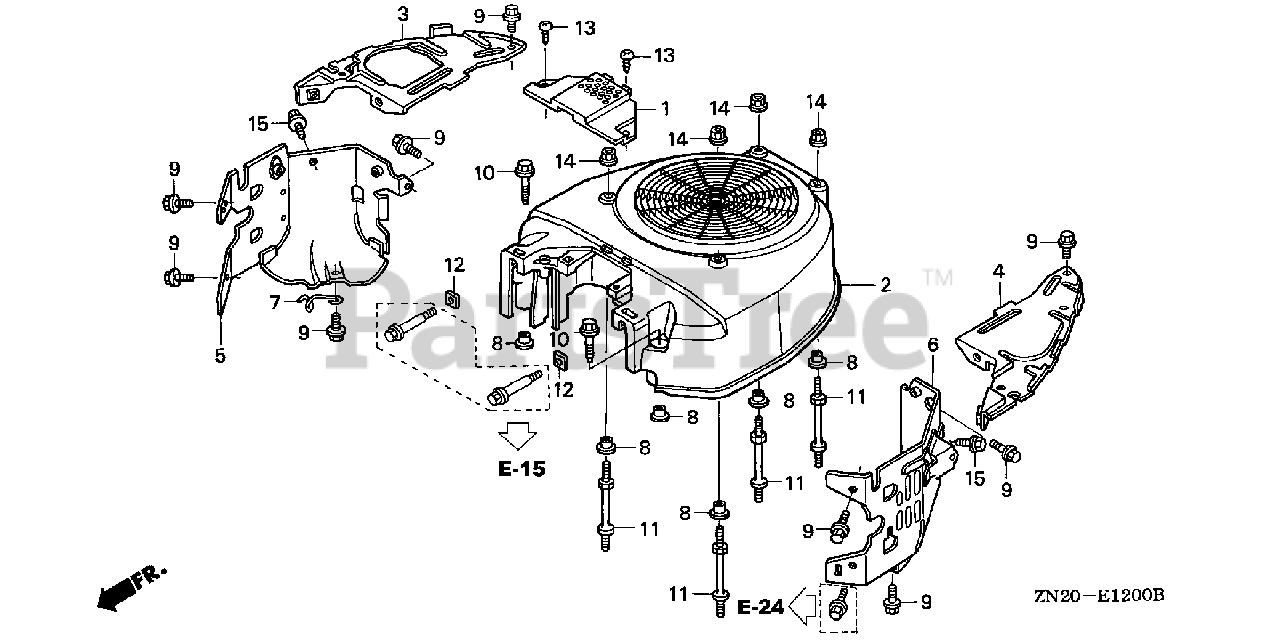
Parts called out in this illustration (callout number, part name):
1	COVER, FUEL PUMP
2	COVER, FAN *NH1* (BLACK)
2	COVER, FAN *R8* (BRIGHT RED)
3	PLATE, R. SIDE
4	PLATE, L. SIDE
5	SHROUD, R.
6	SHROUD, L.
7	CLAMP, IGNITION TUBE
8	COLLAR B, TAILLIGHT
9	BOLT, FLANGE (6X12) (CT200)
10	BOLT, FLANGE (6X23)
11	BOLT, STUD (6X71)
12	NUT, SQUARE (5MM)
13	SCREW, TAPPING (5X20)
14	NUT, FLANGE (6MM)
15	BOLT, FLANGE (6X8)
